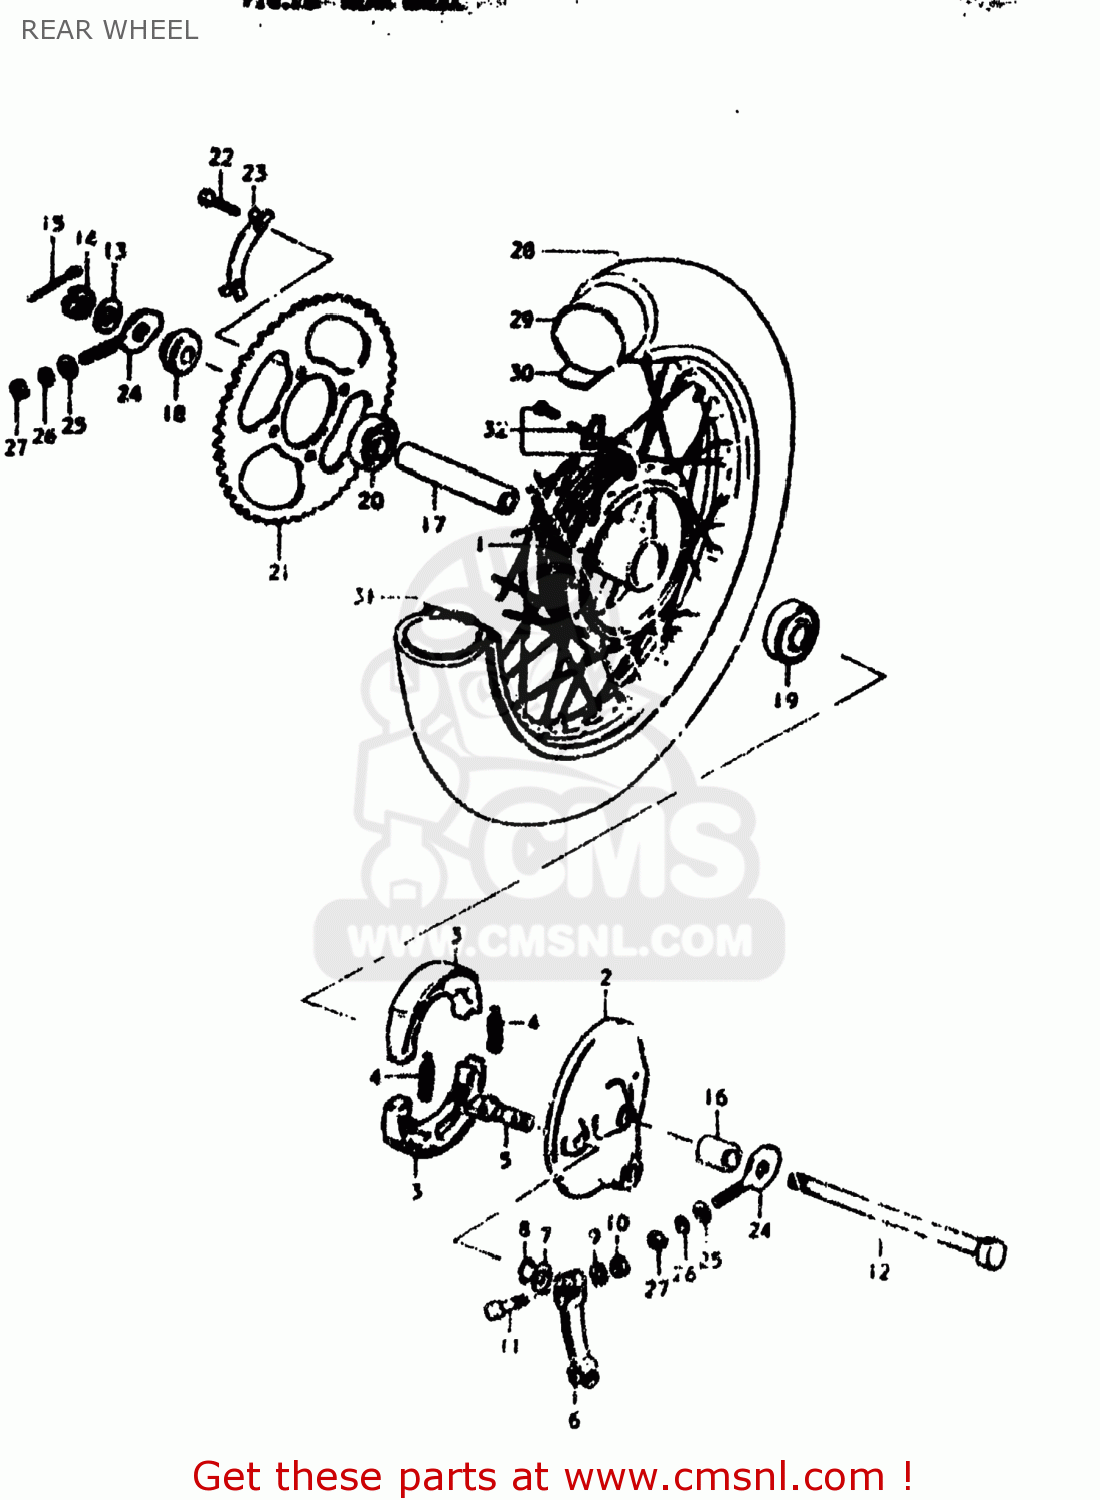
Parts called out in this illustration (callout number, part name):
1	DRUM,REAR HUB
2	PANEL,REAR BRAKE ANCHOR
3	SHOE,BRAKE
4	SPRING(L:34)
5	CAM,FRONT BRAKE
6	LEVER,REAR BRAKE CAM
7	WASHER (14.5X22X1.6)
8	O-RING (D:2.4 ID:13.8)
9	WASHER
10	NUT
11	BOLT(6X33)
12	AXLE,REAR
13	WASHER
14	NUT 12MM
15	COTTER PIN
16	SPACER (12.1X22X27)
17	SPACER(12.6X19X91)
18	SPACER,RR AXLE,L
19	BEARING
20	BEARING
21	SPROCKET,REAR
22	BOLT(8X25)
23	WASHER
24	ADJUSTER,CHAIN,R
25	WASHER
26	LOCK WASHER
27	NUT
28	TIRE
29	TUBE,INNER
30	PROTECTOR,INNER TUBE
31	RIM,RR WHEEL(1.60X12)
32	SPOKE SET,REAR
